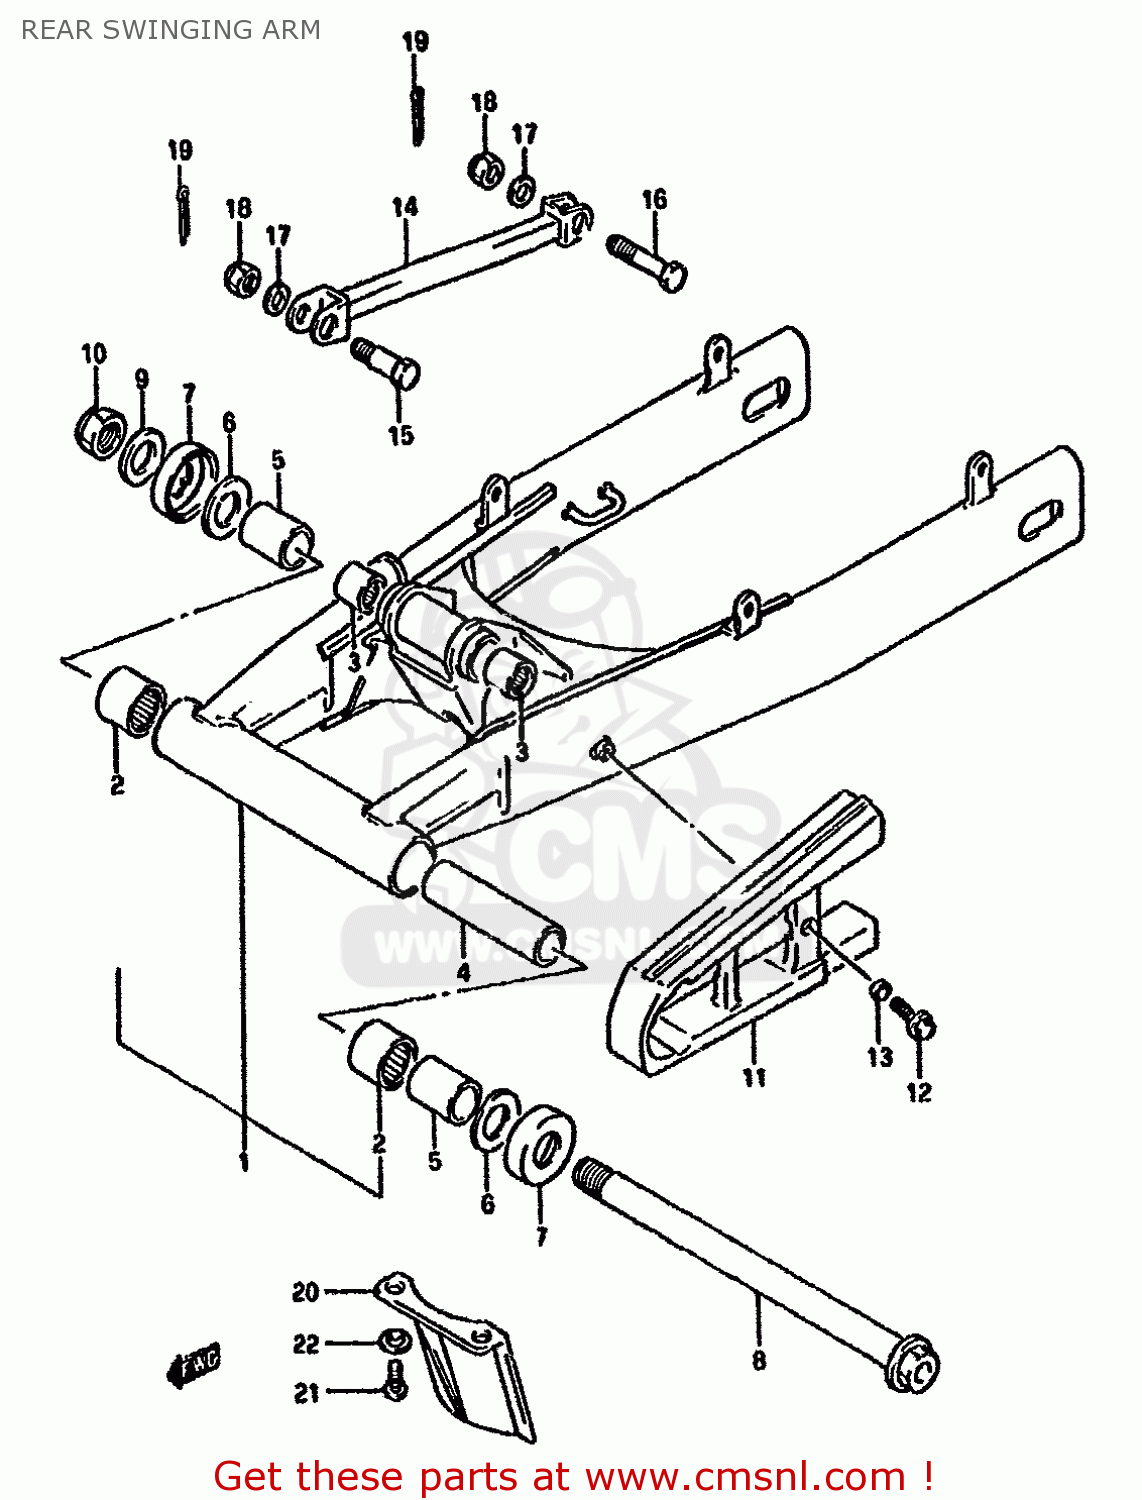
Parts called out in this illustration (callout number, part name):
1	SWING ARM ASSEMBLY,REAR
2	BEARING(25X33X30)
3	BEARING(17X24X25)
4	SPACER(20.8X27.2X146)
5	SPACER,RR SWGARM PIVOT BERRING
6	WASHER
7	COVER,RR SWGARM PIVOT SEAL
8	SHAFT,RR SWINGINGARM PIVOT
9	WASHER
10	NUT
11	BUFFER,CHAIN TOUCH DEFENCE
12	BOLT 6X20,WITH PLAIN WASHER
13	SPACER
14	TORQUE LINK,REAR
15	BOLT
16	BOLT
17	WASHER
18	NUT
19	PIN 20X20
20	GUARD,RR UNIT MUD
21	SCREW
22	WASHER,LOCK
